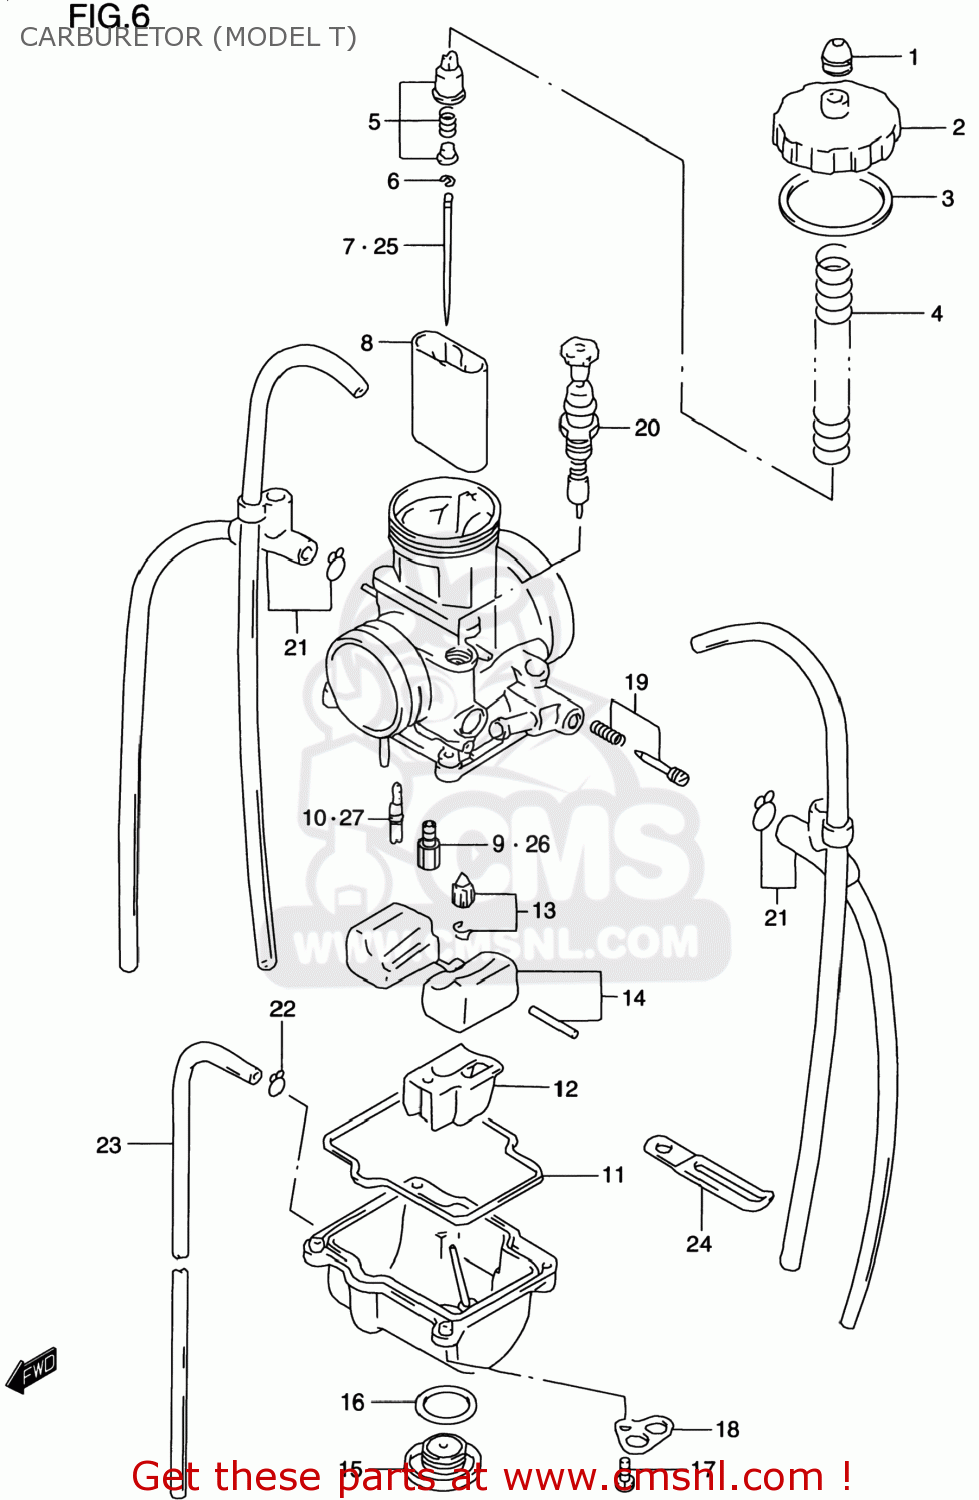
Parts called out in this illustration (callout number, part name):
1	CAP,CARBURETOR
2	CAP,TOP
3	GASKET,TOP CAP
4	SPRING
5	HOLDER SET,CABLE
6	CLIP,NEEDLE
7	NEEDLE(R1467NS)
8	VALVE,PISTON(CA:5.0)
9	JET,MAIN(172)
10	JET,PILOT(58)
11	GASKET,FLOAT CHAMBER
12	HOLDER
13	VALVE SET,FLOAT
14	FLOAT SET
15	BOLT,DRAIN
16	O RING
17	SCREW
18	PLATE
19	SCREW SET,AIR
20	PLUNGER ASSY
21	HOSE SET
22	CLIP
23	HOSE(3.5X6.5X600)
24	CLAMP(L:45)
25	NEEDLE(R1470NS)
26	JET,MAIN(160)
27	JET,SLOW(35)
